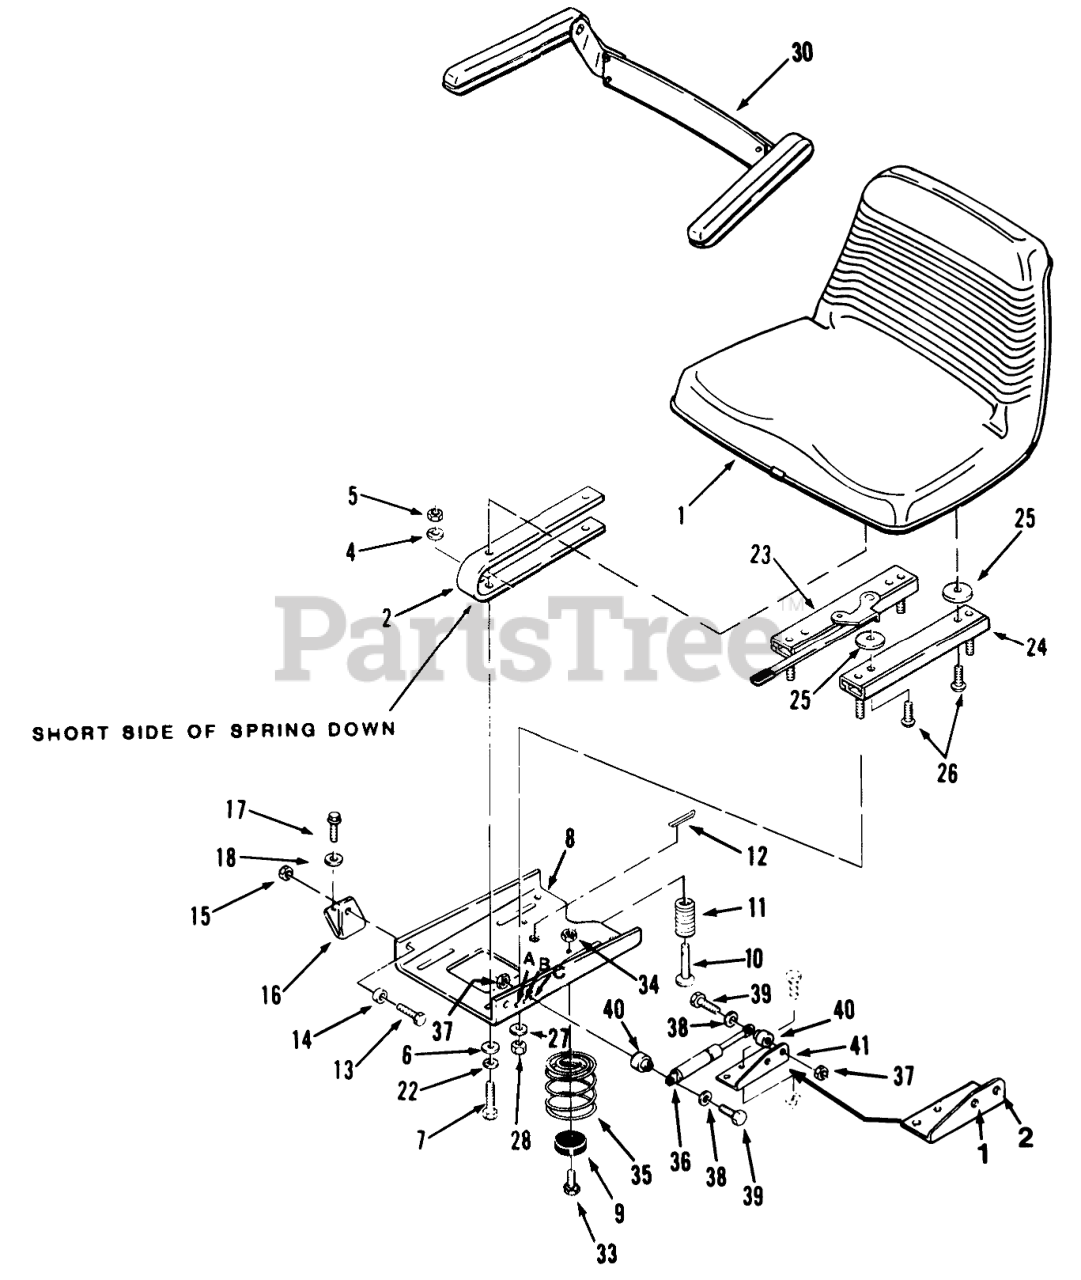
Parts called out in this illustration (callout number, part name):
1	Seat
2	Seat Spring
5	Nut
6	WASHER 5/16 SAE
7	HHCS
8	PLATE-SEAT PIVOT B
9	BUMPER
11	SPRING-SEAT SWITCH
12	Cotter Pin
13	HHCS
14	BUSHING
15	Nut
16	Bracket-Pivot RH
17	Bolt
18	WASHER 5/16 SAE
22	Lockwasher
23	Adjuster-Seat
24	ADJUSTER-R.H. SEAT
25	SPACER-NYLON
26	Screw
28	Nut
30	KIT-ARMREST
33	Bolt
34	Nut
35	SPRING
36	GAS SPRING
37	Nut
39	Bolt
40	SPACER
41	BRACKET-CYLINDER R
